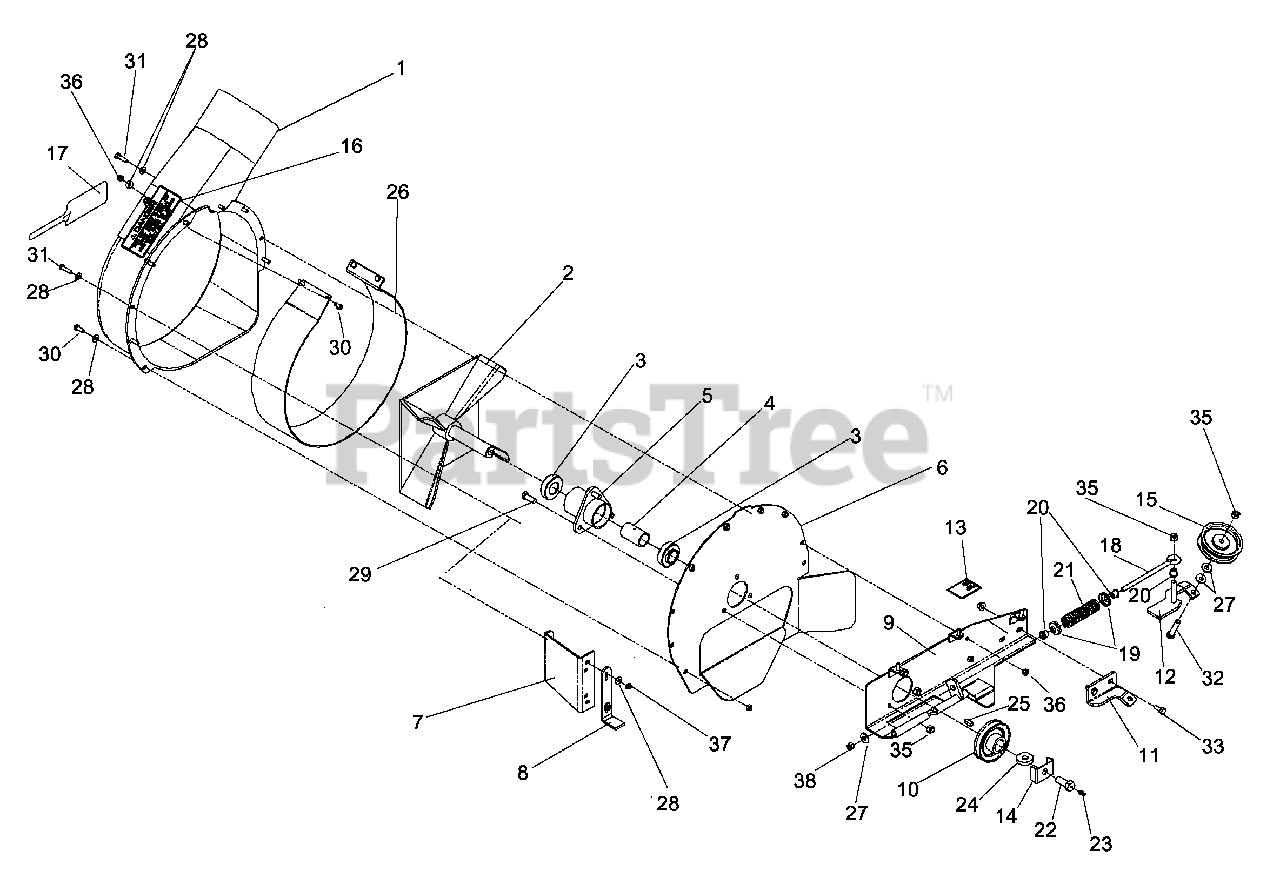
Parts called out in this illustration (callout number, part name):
2	FAN/SHAFT WLDT.
3	BEARING-ECC LOCK
4	SPACER 1 X 2.083
5	HUB WLDT-MACHINED
6	HOUSING PLATE
7	HOUSING GUARD
8	TIP GUARD
9	IDLER BASE WLDT.
10	PULLEY - 3.5
11	PULLEY BRKT.
12	PULLEY SLIDE WLDT.
13	DECAL, ROUTING 42"
15	PULLEY, IDLER 3 METAL
16	G.C.WARNING DECAL
17	DECAL, DIXON
18	EYE BOLT 5/16 X 6.00
19	SPRING RETAINER
20	FLIP-LOK BUSHING
22	HUB BOLT-DRILLED
23	ZERK, 3/16, DRIVE IN
24	WASHER .525 X 1.375 X .25
25	OUTER SHAFT KEY
26	SAND LINER
27	WASHER 5/16 FLAT
28	1/4` SAE FLAT WASHER
29	HCS 3/8C X 1
30	HCS 1/4C X 3/4 HCS
31	HCS 1/4C X 1
32	HCS 3/8-16 X 1 3/4 GR5
33	HCS 5/16C X 3/4
34	5/16-18 FLANGED L-NUT
35	NUT 3/8-16 NYLOC
36	NUT 1/4-20 NYLOC
37	JAM NUT 1/4C
38	NUT 5/16 NYLOC
